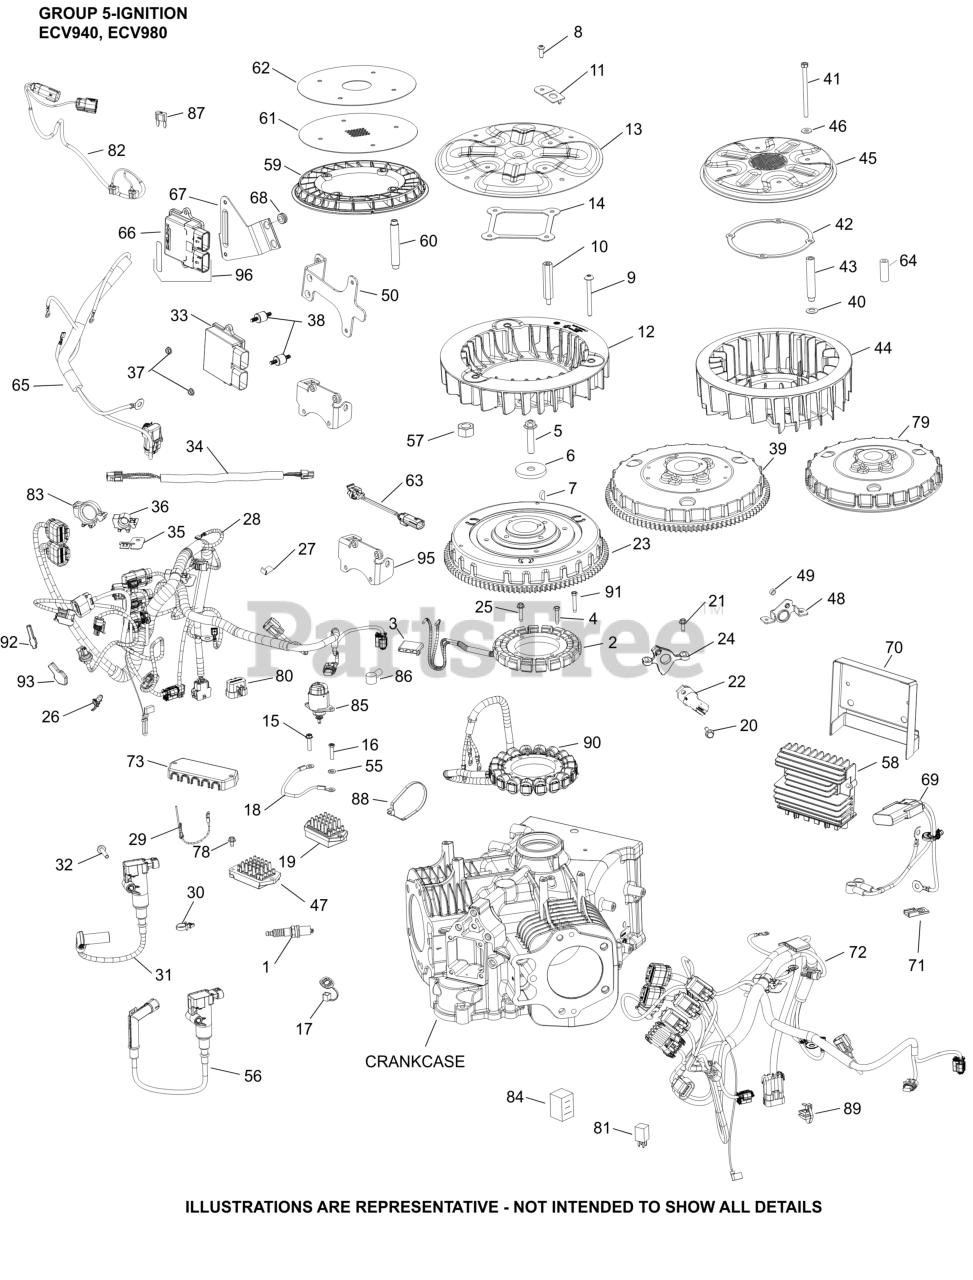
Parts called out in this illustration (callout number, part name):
1	PLUG, SPARK
2	KIT, 15 / 20 AMP STATOR
3	CONNECTOR
4	SCREW, THREAD FORMING
5	SCREW, FLG M10X1.5X45-USE 25 086 361-S
6	WASHER, FLAT 13/32"
7	KEY, 3/16" X 5/8"
15	SCREW, HEX FLANGE HI-LO
21	SCREW, THREAD FORMING
22	SENSOR, SPEED
25	SCREW, THREAD FORMING
27	CLIP, BLOWER HOUSING
31	COIL, IGNITION - EFI
37	NUT, FLG M5X.8
38	ISOLATOR, VIBRATION STUD
39	FLYWHEEL, ASSEMBLY
40	WASHER, SPRING 10 MM
41	SCREW, HEX HEAD
42	RING, SUPPORT
43	SPACER, GRASS SCREEN
44	FAN-(#6215706S)
45	SCREEN, GRASS
46	WASHER, FLAT 1/4" (O.D. 5/8")
47	REGULATOR, RECT (20-30AMP, FW W/OVP)
48	BRACKET, CRANK SENSOR
66	MODULE, ECU MT05.3-USE 25 584 29-S
72	HARNESS, WIRING (8-BAY, EFI-ETB)
78	SCREW, THREAD FORMING
80	CAP, DIAGNOSTIC (8-WAY)
89	TIE, WIRE EDGE FIXED
